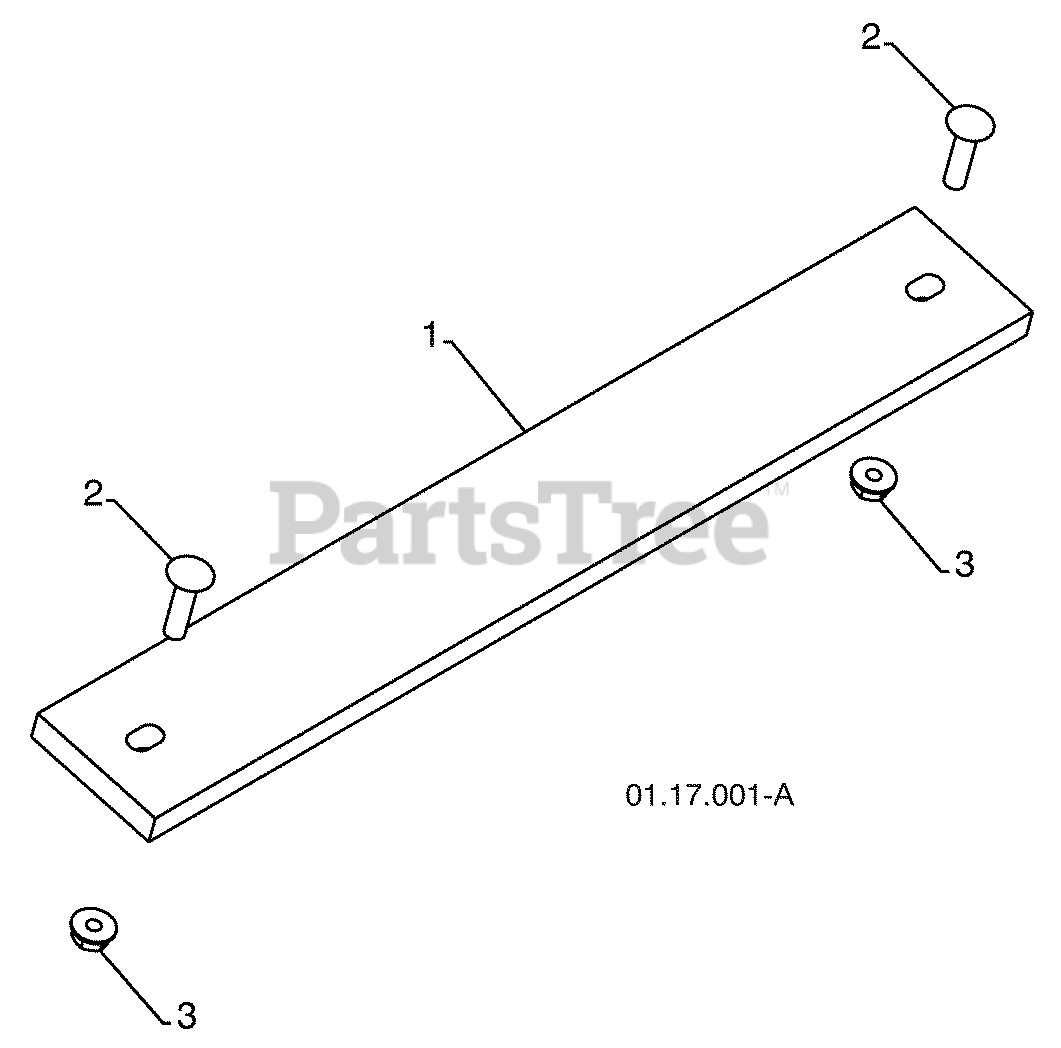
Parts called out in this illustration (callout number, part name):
1	WEIGHT BAR
2	CARRIAGE BOLT 5/16-18 X 1.25
3	NUT 5/16-18
